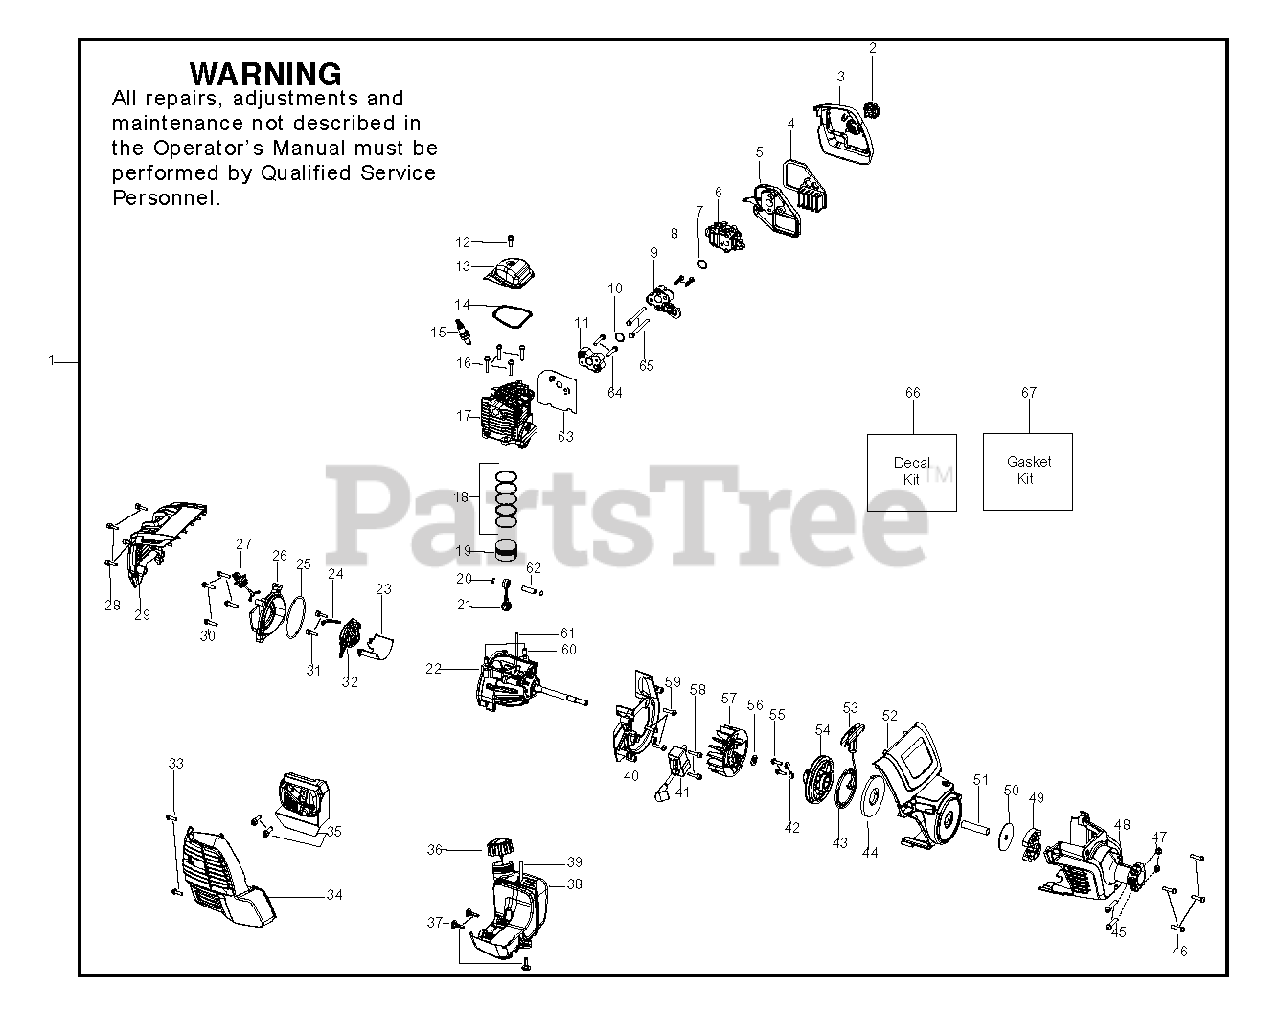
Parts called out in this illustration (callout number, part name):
1	KIT SHORT BLOCK SERVICE
2	ASSY AIRBOX KNOB BLACK
3	KIT AIRBOX COVER SERVICE
4	Air Filter, Felt
5	KIT AIRBOX BASE SERVICE
6	CARBURETOR
7	RING CARB SEALING
9	ADAPTER KIT CARB SERVICE
10	RING CARB SEALING
11	KIT ADAPTER CYL SERVICE
12	SCREW M5-0.8 W/COPPER WAS
13	COVER ROCKER
14	SEAL ROCKER COVER
15	PLUG SPARK 10MM
16	SCREW M5-0.80X25MM
17	KIT CYLINDER SERVICE
18	KIT PISTON RINGS SERVICE
19	PISTON PLATED 4S
20	WRIST PIN RET.
21	ASSY CONNECTING ROD 4S
22	KIT CRANKCASE SERVICE
23	BAFFLE CRANKCASE
24	HOSE MOLDED BREATHER
25	SEAL REAR PLUG
26	PLUG REAR
27	RETAINER OIL CAP
29	KIT REAR SHROUD SERVICE
30	SCREW M5 0.8 X 20MM
31	SCREW M4 0.7 X 16MM
32	KIT BREATHER ASSY SERVICE
33	SCREW 8-16 X 9/16 (PLAS
34	COVER MUFFLER BLACK
35	KIT MUFFLER SERVICE
36	FUEL CAP ASSY W/RETAINER
37	RETAINER FUEL TANK
38	FUEL TANK ASSY
39	FUEL LINE KIT
40	SCROLL 4S
41	MODULE IGNITION 4S
42	RETAINER
43	ROPE ASSY STARTER
44	SPRING STARTER SA
45	SCREW M5-0.80X25MM
46	SCREW M5 0.8 X 20MM
48	ASSY CLUTCH COVER BLACK
49	ASSEMBLY CLUTCH
50	WASHER-CLUTCH
51	SPACER FLYWHEEL
52	ASSY FAN HSG 4S
53	HANDLE STARTER ROPE
55	SCREW 8-16 X 9/16 (PLAS
56	WASHER CLUTCH
57	FLYWHEEL ASSY
58	SCREW M4-0.7X22.225MM
59	SCREW M5 0.8 X 20MM
60	PIN ALIGNMENT 4S
61	HOSE BREATHER SHORT
62	PISTON PIN
63	GASKET AIRDAM
64	SCREW M5-0.80X25MM
65	BOLT CARBURETOR 4S30 55MM
66	KIT DECAL
67	KIT GASKET SERVICE
